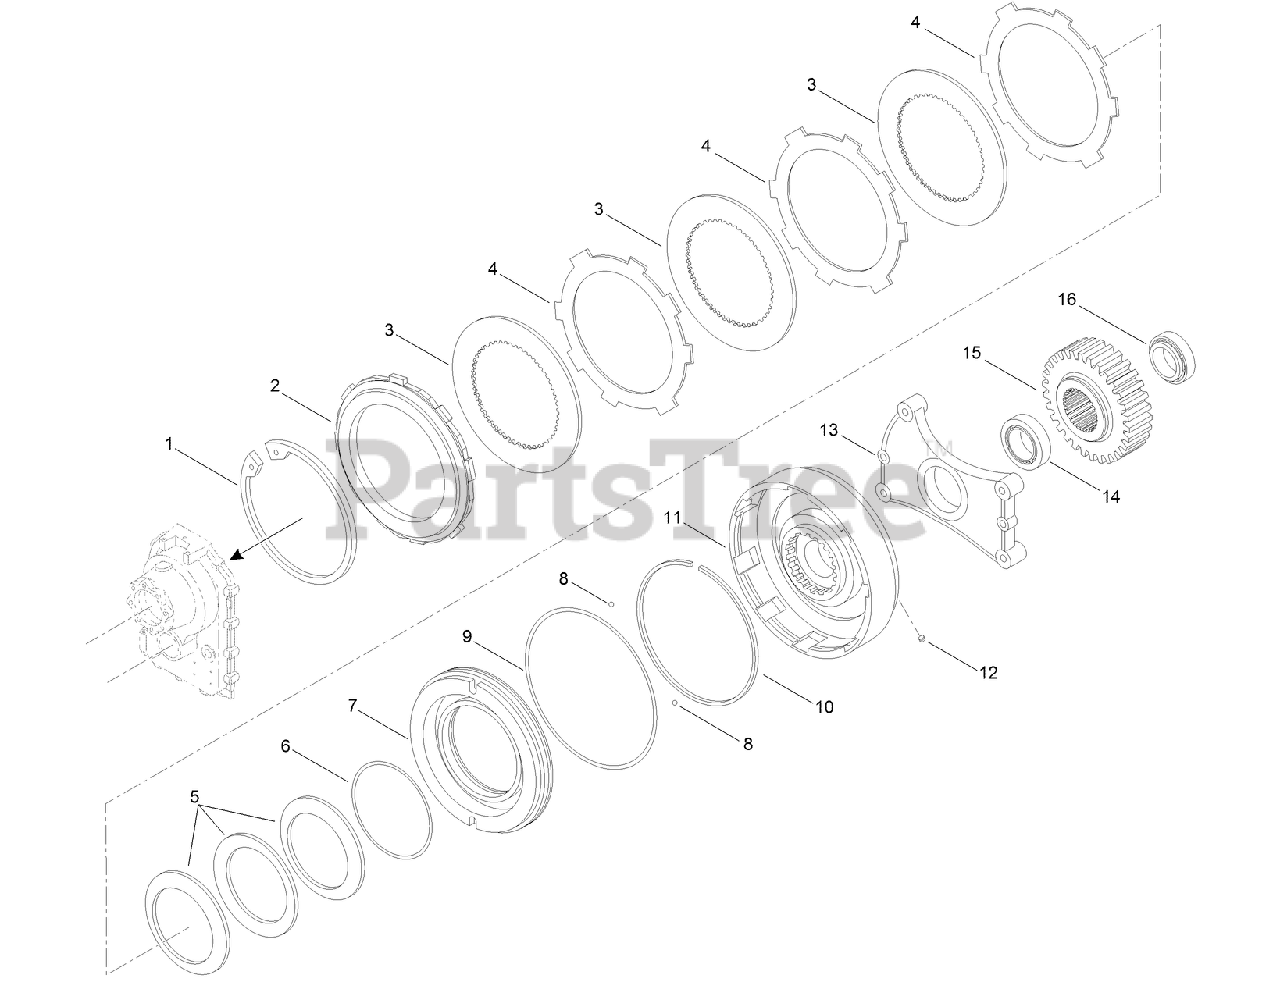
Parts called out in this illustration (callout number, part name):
1	RING-SNAP, INT
2	PLATE-BACK
4	PLATE-SEPARATOR
5	WASHER-CUSHION, CLUTCH
7	PISTON-CLUTCH
10	RING-EXTERNAL
11	HOUSING-CLUTCH
13	HOUSING-WEB, CENTER
14	BEARING-TAPER
15	GEAR-DRIVE, DROP SET
16	BEARING-TAPER
